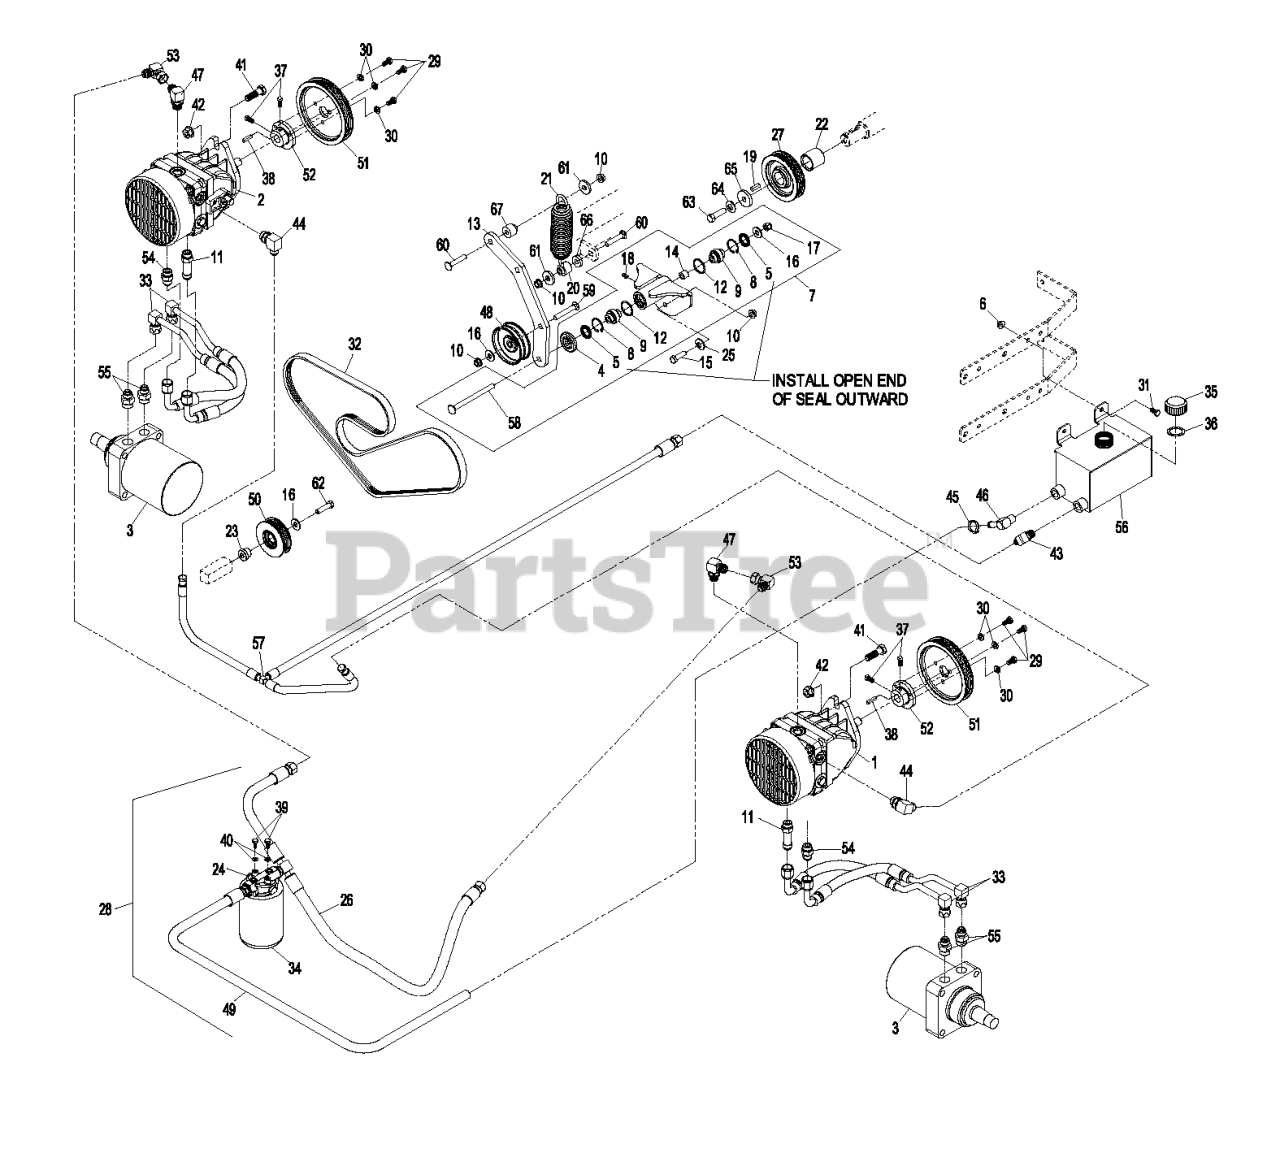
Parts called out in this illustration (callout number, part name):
4	GUARD-TOP
5	SEAL-LIP, SINGLE
7	KIT,XS PUMP IDLER
8	RING-SNAP
9	BEARING-SPHERICAL
10	NUT-HHF, WHIZ
11	ADAPTER-STR, LONG
13	ARM, XS HYDRO TIGHTENER
15	SCREW-HH
16	WASHER-FLAT
17	NUT-LOCK, NI
18	FITTING-GREASE
19	KEY-SQUARE
20	SPACER-SPRING, FAN PUMP
22	SPACER,ENGINE SHEAVE
23	SPACER,LOWER FRAME IDLER
24	HEAD-FILTER
25	WASHER-BELLEVILLE
26	HOSE,31 EPS PUMP INLET
27	SHEAVE,5K 4"PD POLY-V
29	SCREW-HH
30	WASHER-LOCK
31	SCREW-HH
32	BELT,PVK 5 X 70.5
33	HYD HOSE ASM
34	FILTER,XP HYD 25 MICRON
36	GASKET-CAP, TANK
37	SCREW-SET
39	SCREW-HH
40	WASHER-LOCK
41	SCREW-HH
42	NUT-HHF
43	FITTING-ELBOW, 90 DEG
44	FITTING-ELBOW, 90 DEG
46	FITTING-90 DEG
47	FITTING-90 DEG
48	IDLER,PUMP
49	FILTER INLET HOSE ASM
50	ASM,LOWER FRAME IDLER
51	SHEAVE,5K 5.6" PD POLY-V
52	HUB-PUMP
53	FITTING-90 DEG
54	FITTING-STRAIGHT
55	FITTING-STRAIGHT
56	KIT,HYD TANK W/DECALS
57	ASM,CASE DRAIN HOSE XS
58	BOLT CARR 3/8-16X5
59	SCREW-CARR
60	SCREW-HH
62	SCREW-HH
63	SCREW-HH
64	WASHER-SPRING
65	WASHER-CLUTCH
66	SPACER-BRACKET, GUIDE
